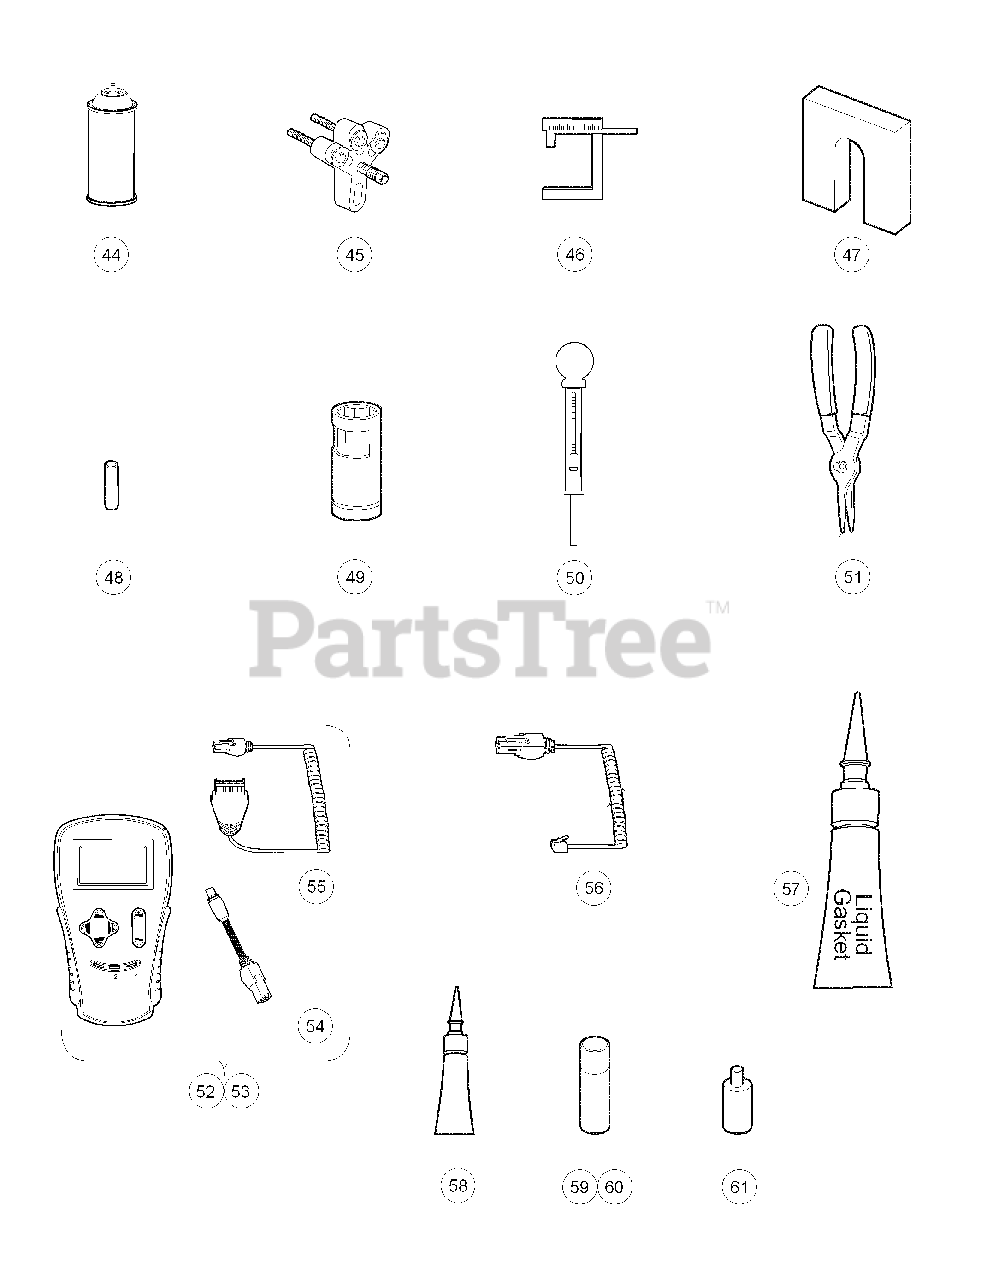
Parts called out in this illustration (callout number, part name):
44	Dry Moly Lubricant
45	Flywheel Puller Kit
46	Gauge, Carburetor Float Level
48	Governor Shaft Installation Tool
49	Hydraulic Brake Adjuster
50	Hydrometer
51	Internal Retaining Ring Pliers
52	IQ Display Module Kit
53	IQ Display Module Kit
54	Adaptor, Cable
55	IQDM Series 2 Cable
56	IQDM Series 1 Cable
57	Liquid Gasket
58	Moly-Teflon Lubricant
59	Paint, Touch-Up – Beige
59	Paint, Touch-Up – Black
59	Paint, Touch-Up – Burgundy
59	Paint, Touch-Up – Classic Blue
59	Paint, Touch-Up – Dark Gray
59	Paint, Touch-Up – Dark Green
59	Paint, Touch-Up – Gray
59	Paint, Touch-Up – Red
59	Paint, Touch-Up – Royal Blue
59	Paint, Touch-Up – White
60	Paint, Precedent Underbody – Gray
61	Paint Pen, Touch-Up, Precedent Underbody – Black
